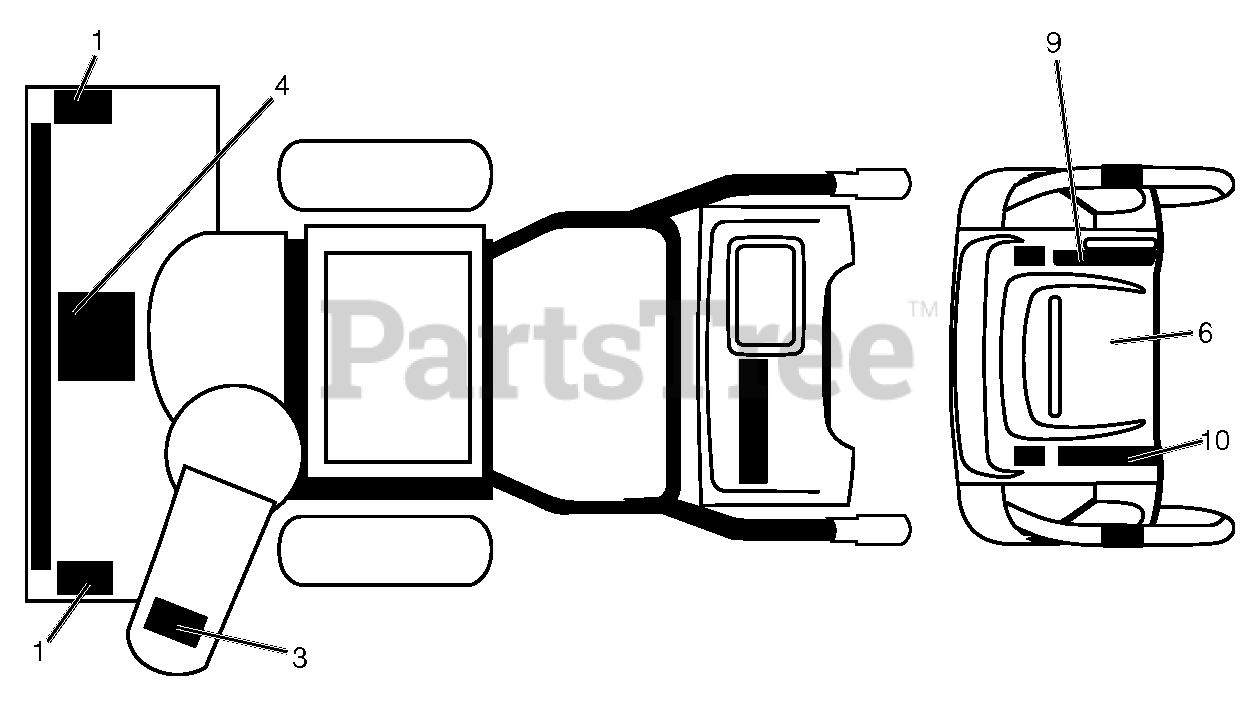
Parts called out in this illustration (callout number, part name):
1	DECAL.SNOWTHR.AUGER
3	Decal, Snow Thrower Chute Safety
4	Decal, Snow Thrower Read Owner's Manual E/F
6	Instruction Panel Decal
9	RP.DECAL.CONS.RT.SPD/LEV/PWRST
